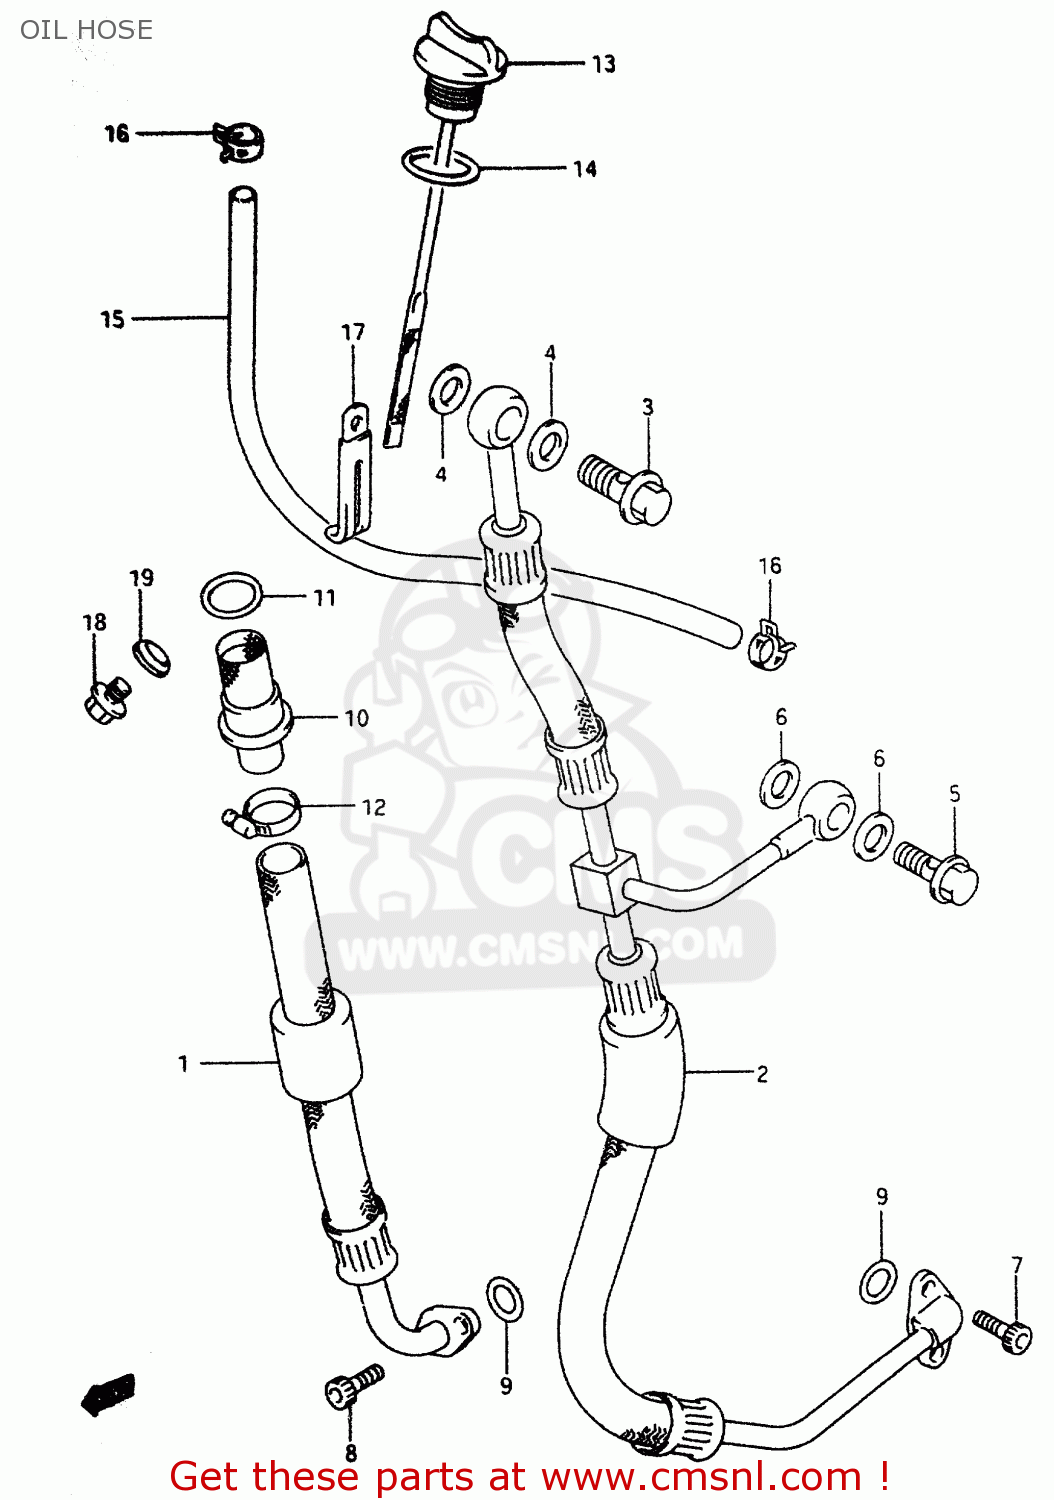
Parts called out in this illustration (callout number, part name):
1	HOSE,OIL TANK INLET
2	HOSE,OIL TANK
3	BOLT UNION
4	GASKET(16X22X2) (NAS)
5	BOLT UNION
6	GASKET(12X17X1) (NAS)
7	BOLT,OIL FILLE
8	BOLT,CRKCASE,R
9	O RING(D:2.4,ID:12.3)
10	STRAINER,FRAME HEAD UNDER
11	O RING(D:3.1,ID:22.7)
12	CLAMP
13	GAUGE ASSY,OIL LEVEL
14	O RING(D:3.1,ID:16.8)
15	HOSE,OIL OVER FLOW
16	CLIP
17	CLAMP(L:45)
18	PLUG(10X12)
19	GASKET(10X14X3.6) (NAS)
